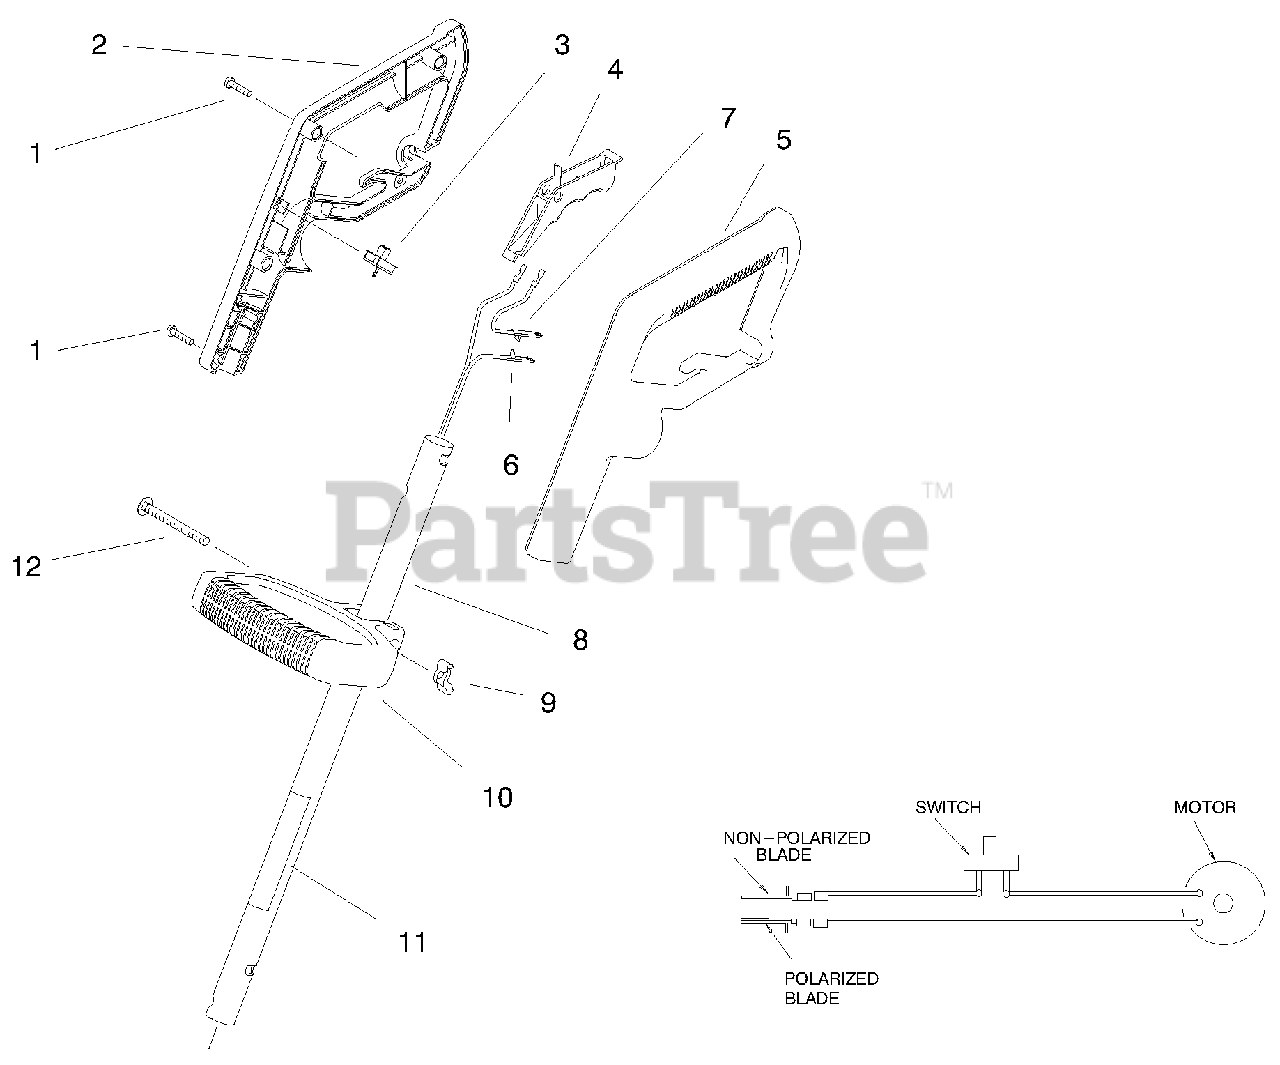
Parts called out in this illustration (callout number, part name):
1	SCREW-PPH
2	GRIP-HAND,RH
5	GRIP-HAND,LH
6	HARNESS-WIRE
7	WIRE-ASSEMBLY,JUMPER
8	Tube Assembly (Incl. Ref. #11)
9	1/4"-20 STAMP WNG NUT
10	MID HANDLE
11	DECAL-WARNING
12	SCREW-CARR.25-20 X 2.50
